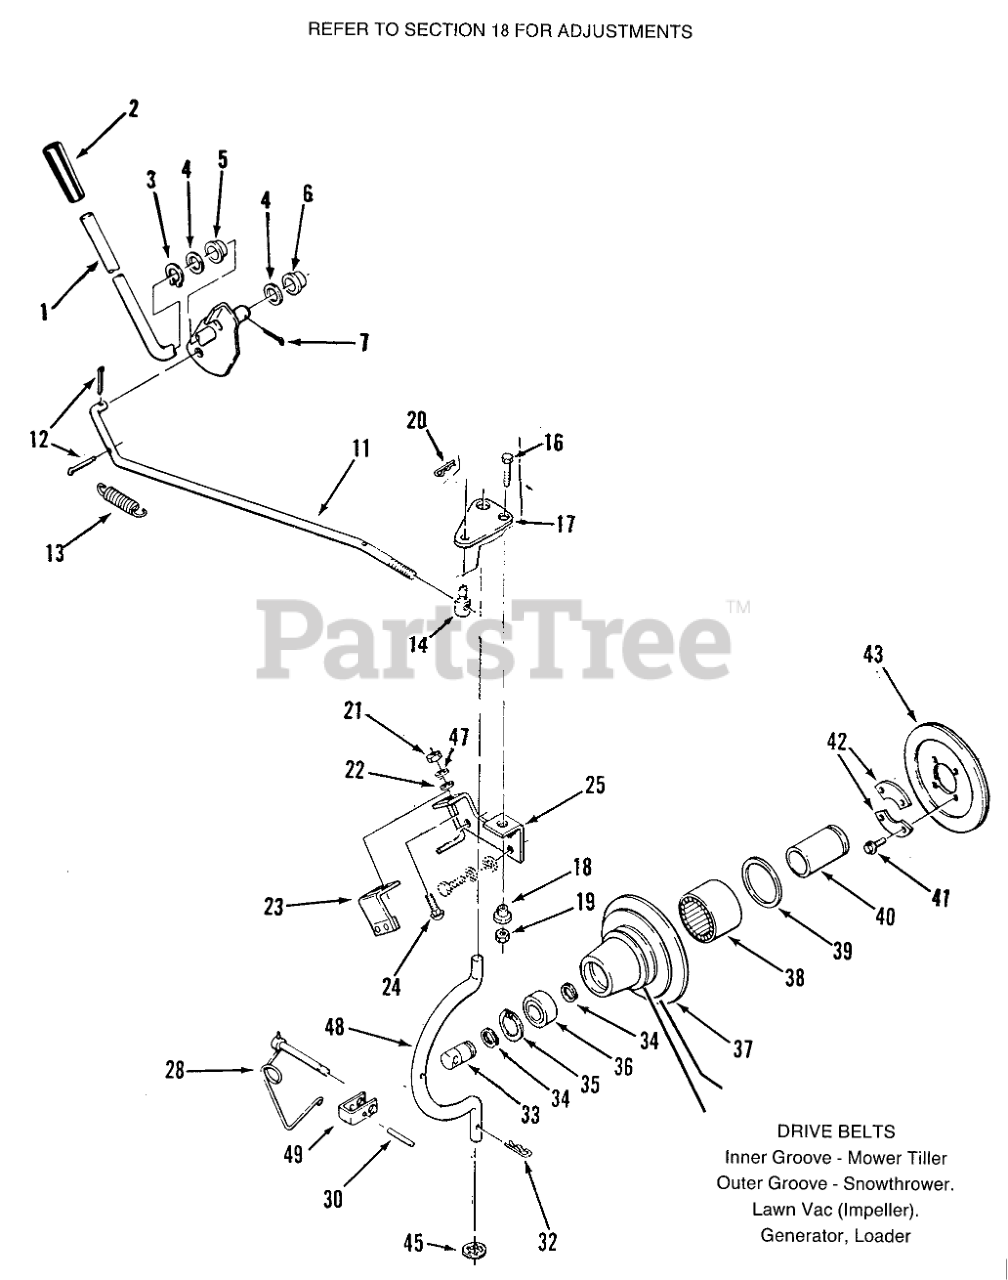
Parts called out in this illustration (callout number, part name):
1	ASSY PTO CLUTCH LEVE
2	GRIP
3	Grip Ring
4	SHIM-WASHER
5	BUSHING-NYLINER
6	NYLINER BUSHING
7	Pop Rivet
11	ROD-PTO CLUTCH
12	Pop Rivet
13	SPRING
14	TRUNNION
16	BOLT
17	PLATE
18	SPACER-LIFT LINK
19	Nut
20	Hairpin Cotter
21	Nut
23	ASM-Bracket
24	Bolt-Carriage
25	ASS'Y-ENGINE BRKT B
28	LOCKING PIN ASM
29	CLEVIS
31	ASS'Y-GAUGE CAP
32	Hairpin
33	SHAFT-PTO
34	RING-SNAP, EXTERNAL
35	Ring-Snap
36	BEARING-BALL
37	Housing-Clutch
38	BRG-NEEDLE OPEN END
39	SEAL-OIL
40	RACE-BEARING
41	H H C S
42	RETAINER
43	Clutch Plate & Facing
45	RING-REINFORCED CIRC
47	Washer
